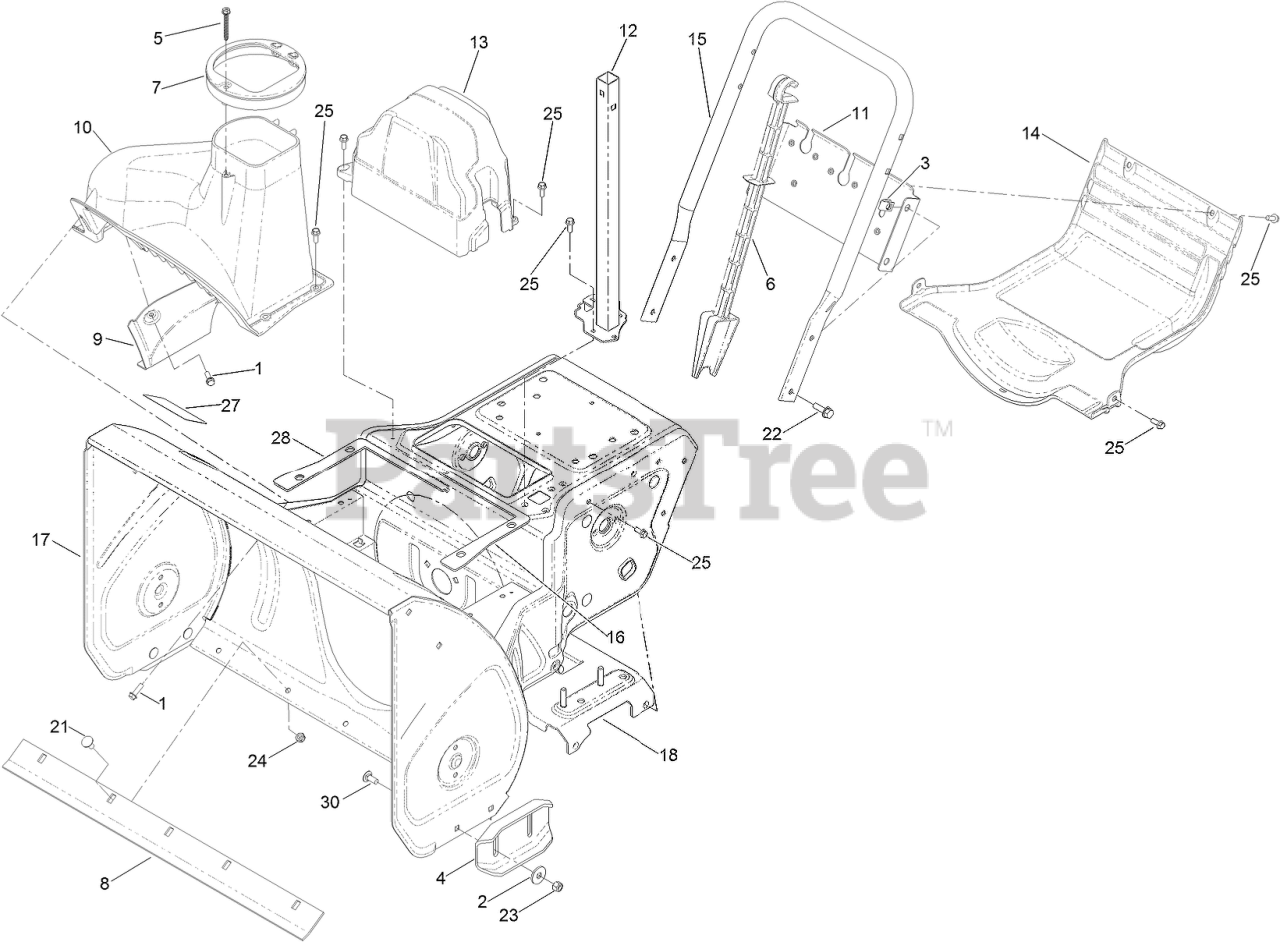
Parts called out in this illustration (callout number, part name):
1	SCREW-HWH
2	WASHER
3	NUT-U
5	SCREW-HWH, PLASTITE
6	STICK-CLEANOUT
7	GUIDE-CHUTE
8	SCRAPER-24 INCH
9	COVER-LINER
11	BRACE-FRAME
12	SUPPORT-CHUTE
13	COVER-BELT
14	COVER-LOWER
15	HANDLE-LOWER
16	SEAL-HOUSING, LH
17	FRAME
18	PLATE-STUD ENGINE
21	SCREW-CARR
22	SCREW-HHF
23	NUT-LOCK, NI
24	NUT-LOCK, NI
25	SCREW-HWH
27	DECAL-DANGER, AUGER
28	SEAL-HOUSING, RH
30	SCREW-CARR
